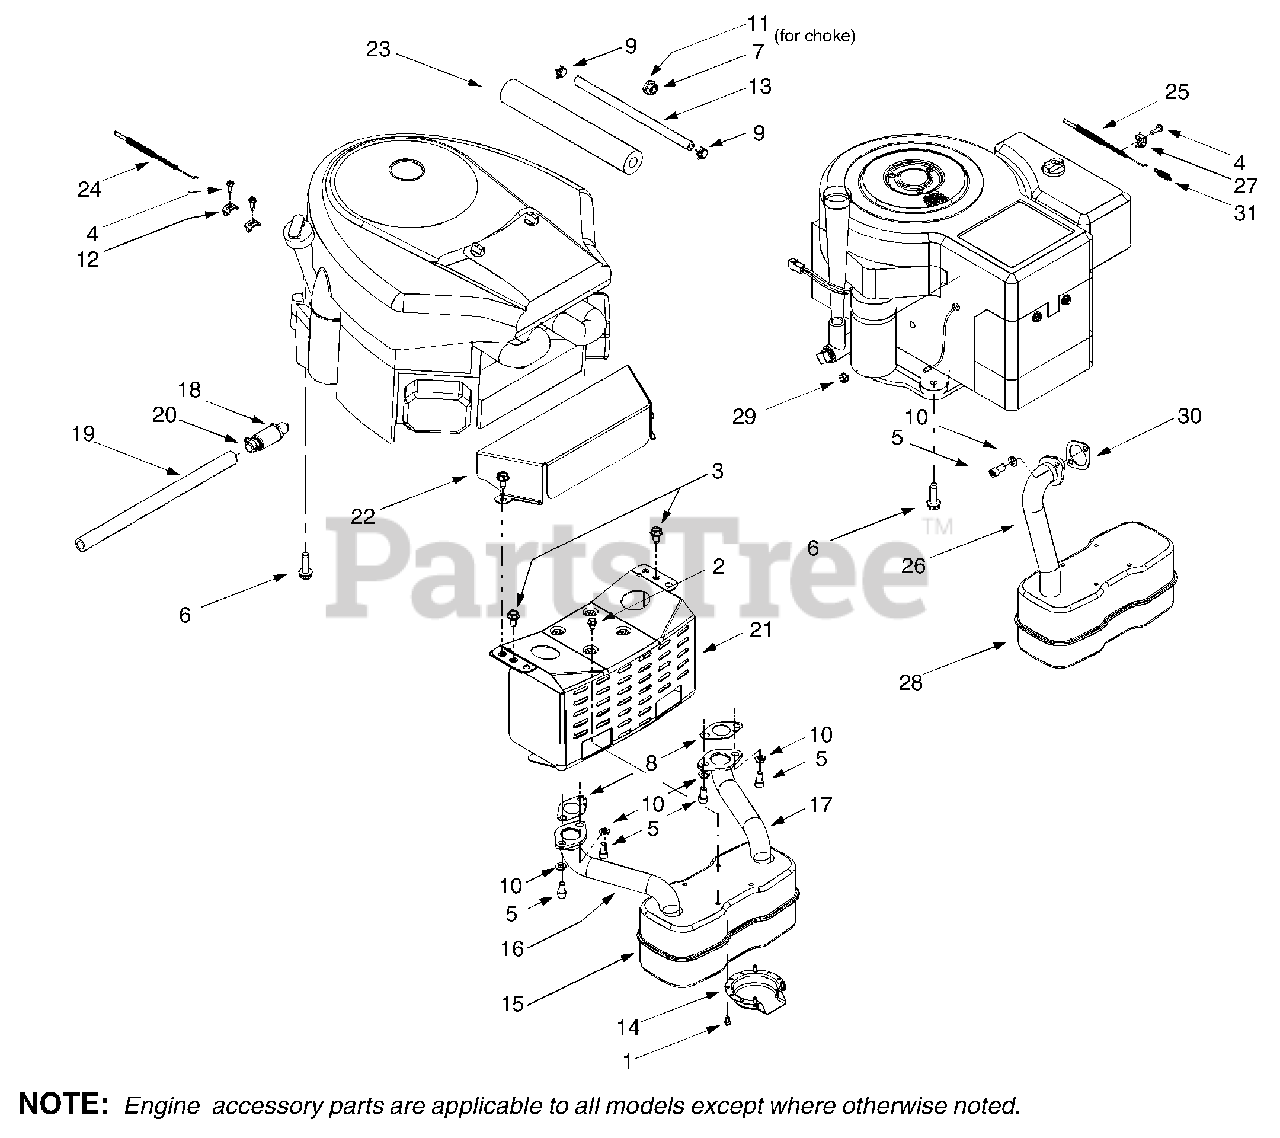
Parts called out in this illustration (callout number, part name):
1	Self-tapping Screw, #8-18 x .5
2	Self-tapping Screw, 1/4-20 x .5
3	Self-tapping Screw, 5/16-18 x .625
4	Screw, #10-32 x .625
5	Socket Cap Screw, 5/16-18 x .625
6	Self-tapping Screw, 3/8-16 x 1.25
7	Hex Nut, 3/8-16 (Model LTX-2146)
8	Exhaust Gasket (Model LTX-2146)
9	Hose Clamp
10	Lock Washer, 5/16
11	Flat Washer (Model LTX-2146)
12	Casing Clamp (Model LTX-2146)
13	Fuel Line Hose
14	Muffler Deflector
15	Muffler, Twin Inlet (Model LTX-2146)
16	RH Exhaust Pipe (Model LTX-2146)
17	LH Exhaust Pipe (Model LTX-2146)
18	Oil Drain Valve
19	Oil Drain Hose
20	Oil Drain Cap
22	Engine Heat Shield (Model LTX-2146)
23	Foam (over fuel line) (Model LTX-2146)
24	Throttle Cable (Model LTX-2146)
25	Throttle Cable (Model LTX-1842)
26	Exhaust Pipe (Model LTX-1842)
27	Casing Clamp (Model LTX-1842)
28	Muffler, Single Inlet (Model LTX-1842)
29	Hex Sems Nut, 1/4-20 (for starter cable)
30	Exhaust Gasket (Model LTX-1842)
